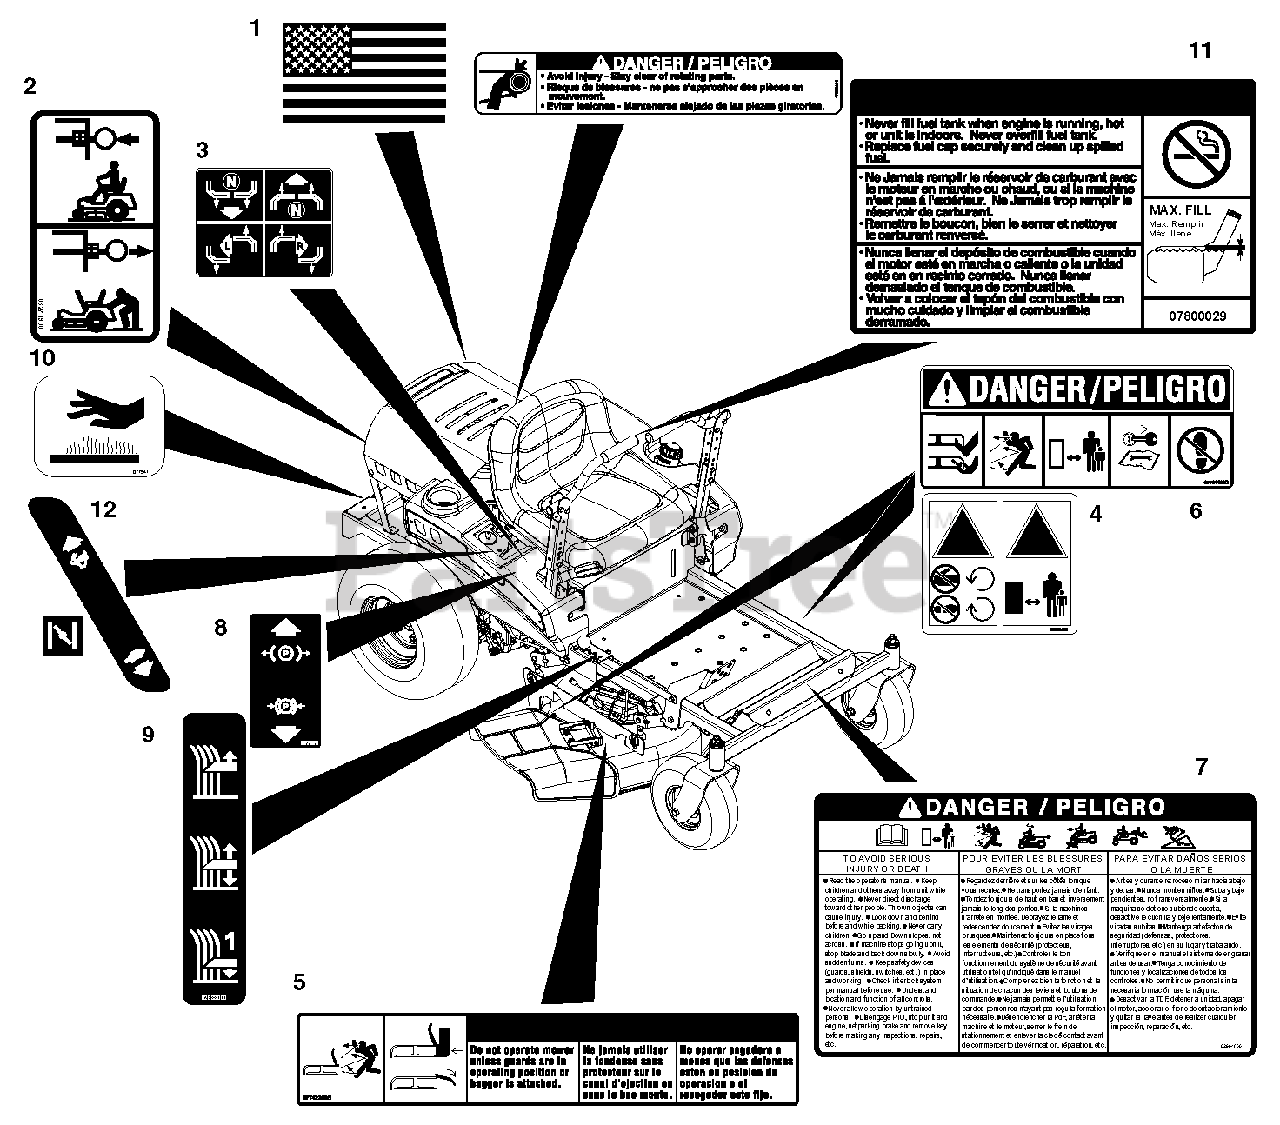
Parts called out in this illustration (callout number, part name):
1	Decal, American Flag
2	Decal, Transmission Disconnect
3	Decal, Instructional Steering
4	Decal, Mower Pan Head Danger
5	Decal, Warning
6	Decal, Cut Height
7	Decal, Bilingual Danger
8	Decal, Parking Brake Lever
9	Decal, Danger
10	Decal, Hot Surface
11	Decal, Fuel Warning
12	Decal, Control
